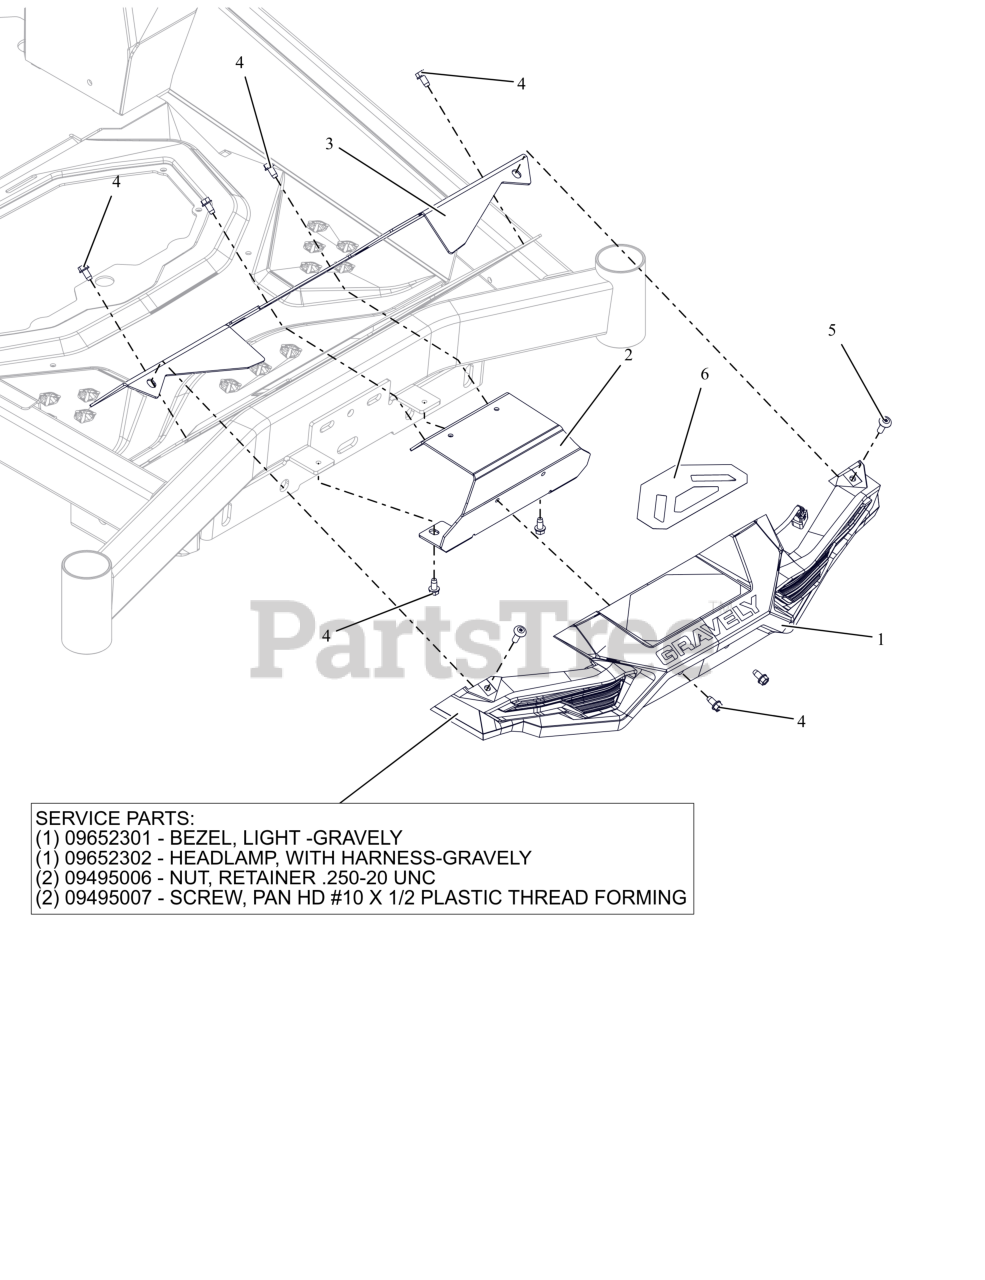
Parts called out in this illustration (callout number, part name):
1	LIGHT ASSY- HEADLIGHT GRAVELY
1	BEZEL LIGHT-GRAVELY
1	HEADLAMP- WITH HARNESS-GRAVELY
1	NUT, RETAINER .250-20 UNC
1	SCREW, PAN HD #10 X 1/2 PLACTIC THREAD FORMING
2	BRKT-FRT FACIA-LOWER-GRAVELY
3	BRKT- FRT FACIA UPPER-GRAVELY
4	SCR-TAP .25X.50 HWH ZB500
5	SCR-MCH .25-20X.75 TXTR ZB500
6	GRIP- TAPE-FRONT STEP-GRAVELY
